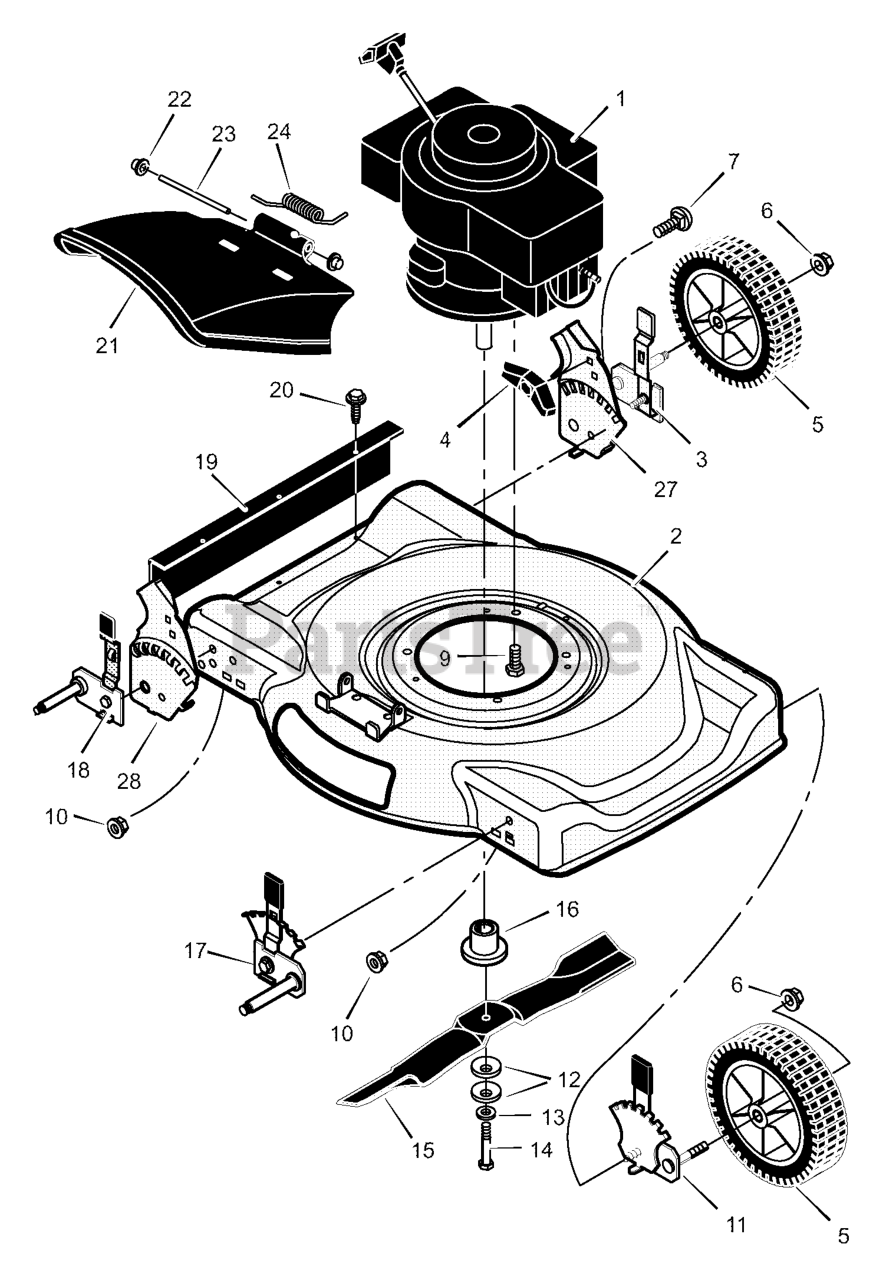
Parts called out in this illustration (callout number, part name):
1	Engine
2	Housing
3	Height Adjuster, Left Rear
5	Wheel and Tire
6	Locknut, Flange
7	Bolt, Carriage
9	Bolt, Engine
10	Nut
11	Height Adjuster, Left Front
12	Washer, Belleville
14	Bolt, Hex
15	Blade, Side Discharge
16	Adapter, Blade
17	Height Adjuster, Right Front
18	Height Adjuster, Right Rear
19	Guard, Rear
21	Deflector, Chute
22	Push-On Cap
23	Pin, Pivot
27	Bracket, Left Handle
28	Bracket, Right Handle
